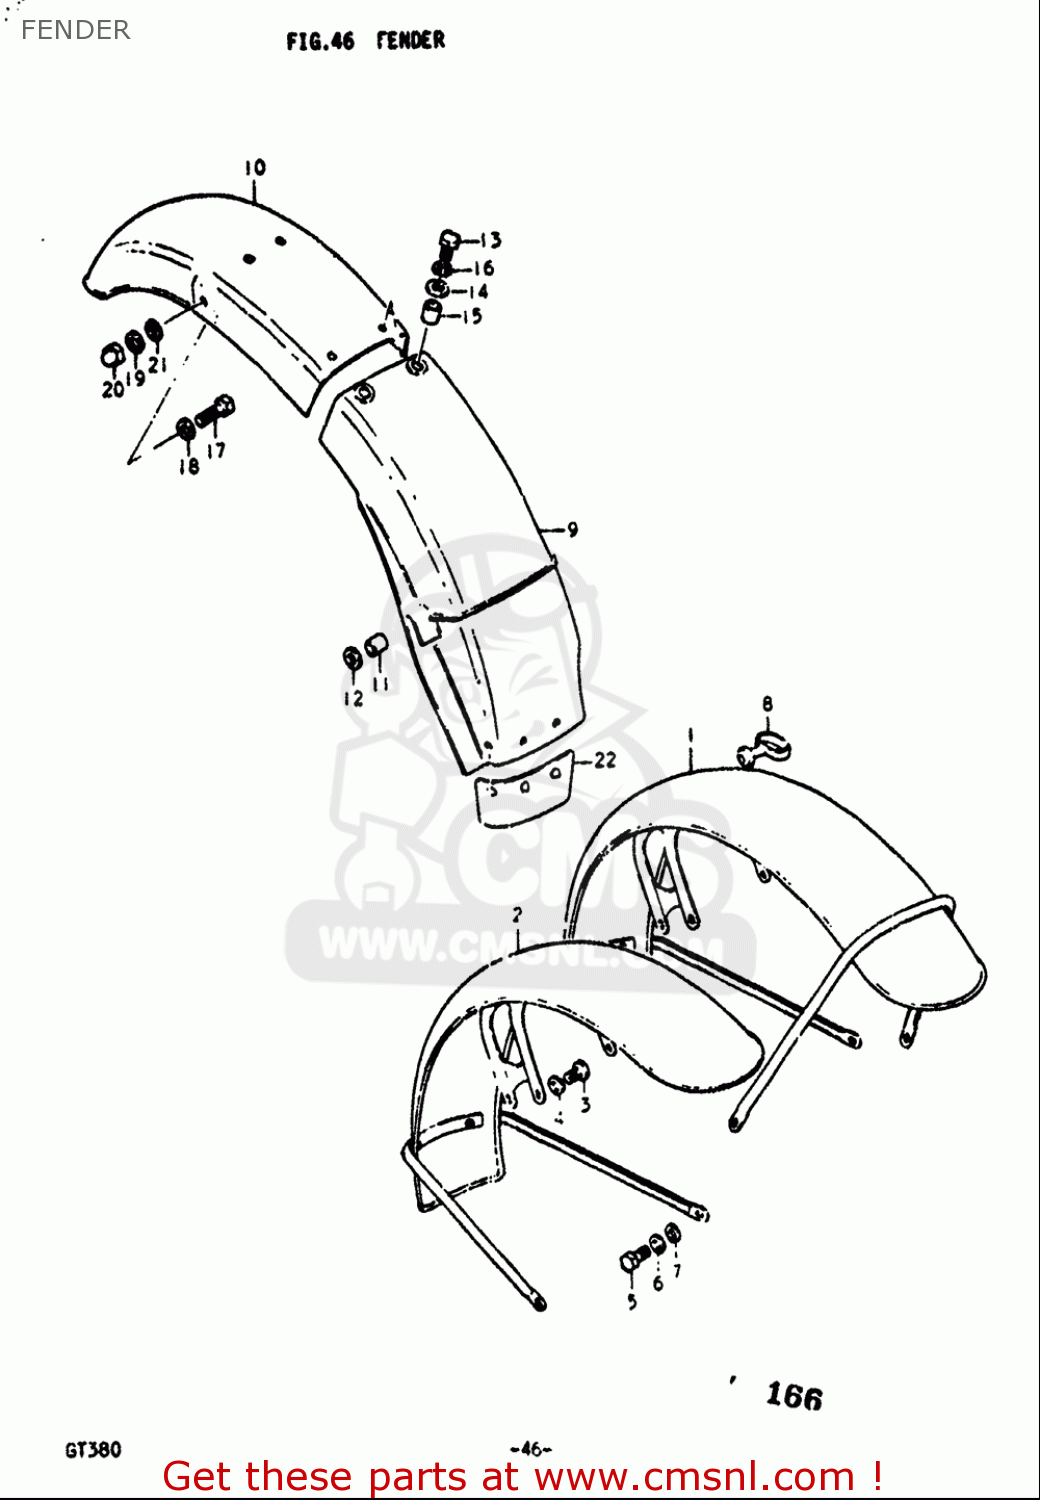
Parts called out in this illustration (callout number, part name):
1	FENDER ASSY,FR
2	FENDER ASSY,FR
3	BOLT
4	WASHER,LOCK
5	BOLT
6	WASHER
7	WASHER,LOCK
8	GUIDE,CABLE
11	CUSHION
12	WASHER(6.5X18X1.6)
13	BOLT
14	WASHER
15	SPACER
16	WASHER,LOCK
17	BOLT
18	WASHER
19	WASHER,LOCK
20	NUT
21	WASHER (8.2X22X3.2)
